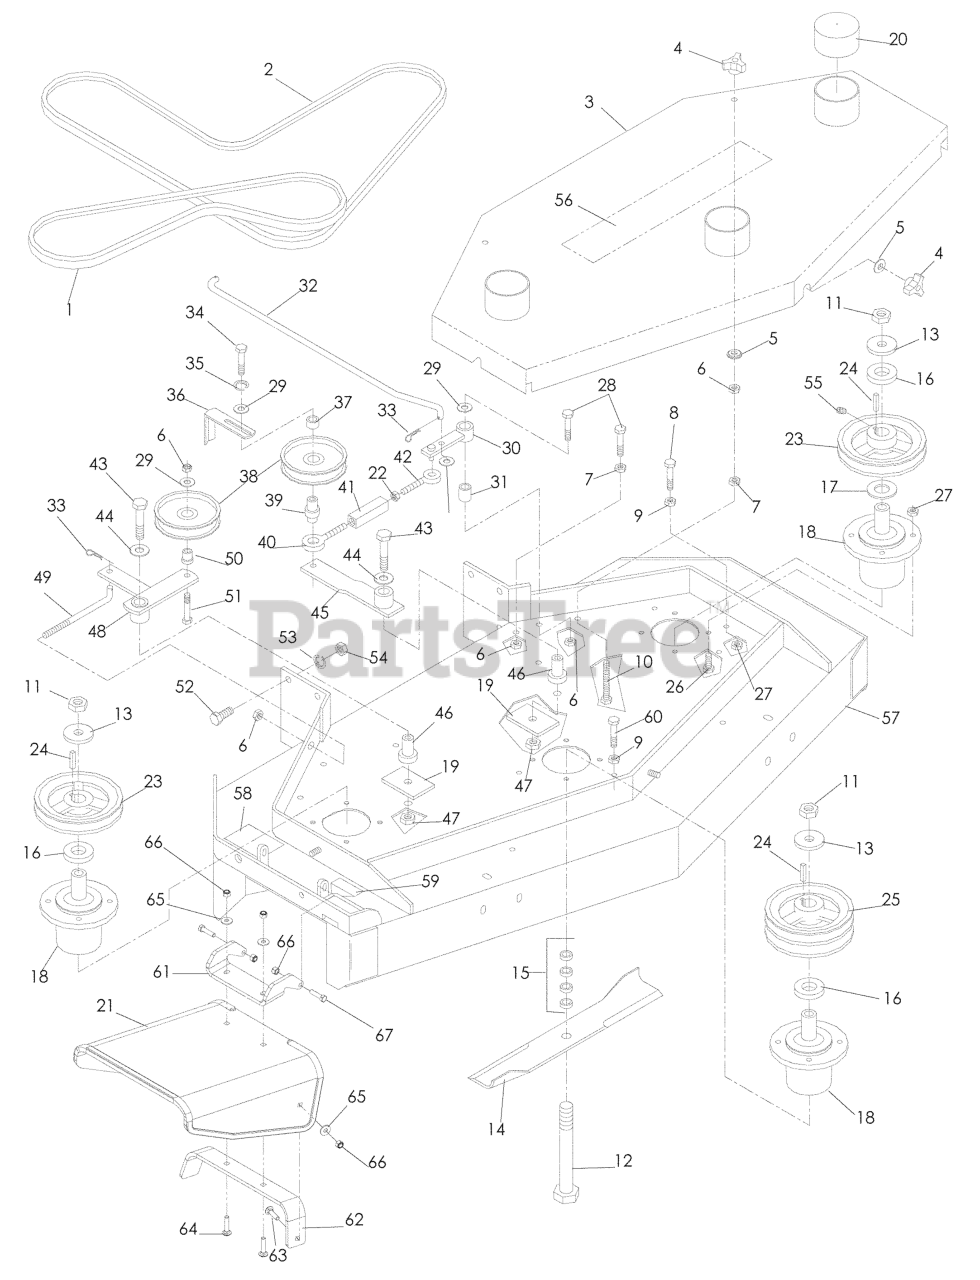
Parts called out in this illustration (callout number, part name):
1	BELT, AUX BLADE
2	BELT - ENG/DECK 48
3	BELT SHIELD 48"
4	KNOB, THREE PRONG
5	WASHER, 3/8 SEALING
6	NUT 3/8C CENTERBLOCK
7	NUT 3/8C WHIZ
8	HCS 5/16 X 3
9	NUT 5/16C WHIZ
10	TAPBOLT 3/8C X 4 1/2
11	NUT 5/8F HEX
12	HCS 5/8F X 8 1/2
13	WASHER, SUPPORT
14	BLADE OEM 16 1/4"
15	BLADE SPACERS
17	MACHINERY BUSHING 10 GA.
18	HOUSING ASM
21	CHUTE, RUBBER DISCHARGE WB
22	NUT 5/16C HEX
23	PULLEY W/SETSCREWS
24	KEY 1/4 SQ X 1 1/8
25	PULLEY, DOUBLE W/SETS
26	HCS 5/16C X 1
27	NUT 5/16C CENTERLOCK
28	HCS 3/8C X 2 1/4
29	WASHER 3/8 FLAT
30	ENGAGEMENT ARM
31	BUSHING, SLEEVE
32	BLADE ROD 48"
33	HAIRPIN #2
34	HCS 3/8C X 2 1/2
35	SLW 3/8 STD
38	IDLER PULLEY
39	EYEBOLT PIVOT
40	EYEBOLT, LH
41	TURNBUCKLE
42	EYEBOLT, RH
43	HCS 1/2C X 2 3/4
44	WASHER 1/2 FLAT
45	ARM WELDMENT
46	IDLER SPINDLE
47	NUT 1/2-13 HEX NYLOC ZD
48	IDLER ARM, AUX.
49	TENSION ROD
50	BUSHING, IDLER FLANGE
51	HCS 3/8-16 X 1 3/4 GR5
52	HCS 7/16C X 1 1/2
53	WASHER 7/16 LOCK
54	NUT 7/16C HEX
55	SET SCREW 5/16 NYLOC
56	DECAL, HUSQ 12" BLUE
57	DECK W/DECALS 48"
58	DECAL, EURO SEVERING
59	DECAL, CPSC
60	HCS 5/16C X 4
61	PIVOT BRACKET - CHUTE
62	BRKT, REINF-CHUTE WB
63	BOLT, CARRIAGE 5/16X1-1/4
64	RHSNB 5/16-18 X 1-1/2 GR 5 ZD
65	WASHER 5/16 FLAT
66	NUT 5/16 NYLOC
67	HCS 5/16C X 1 1/4
